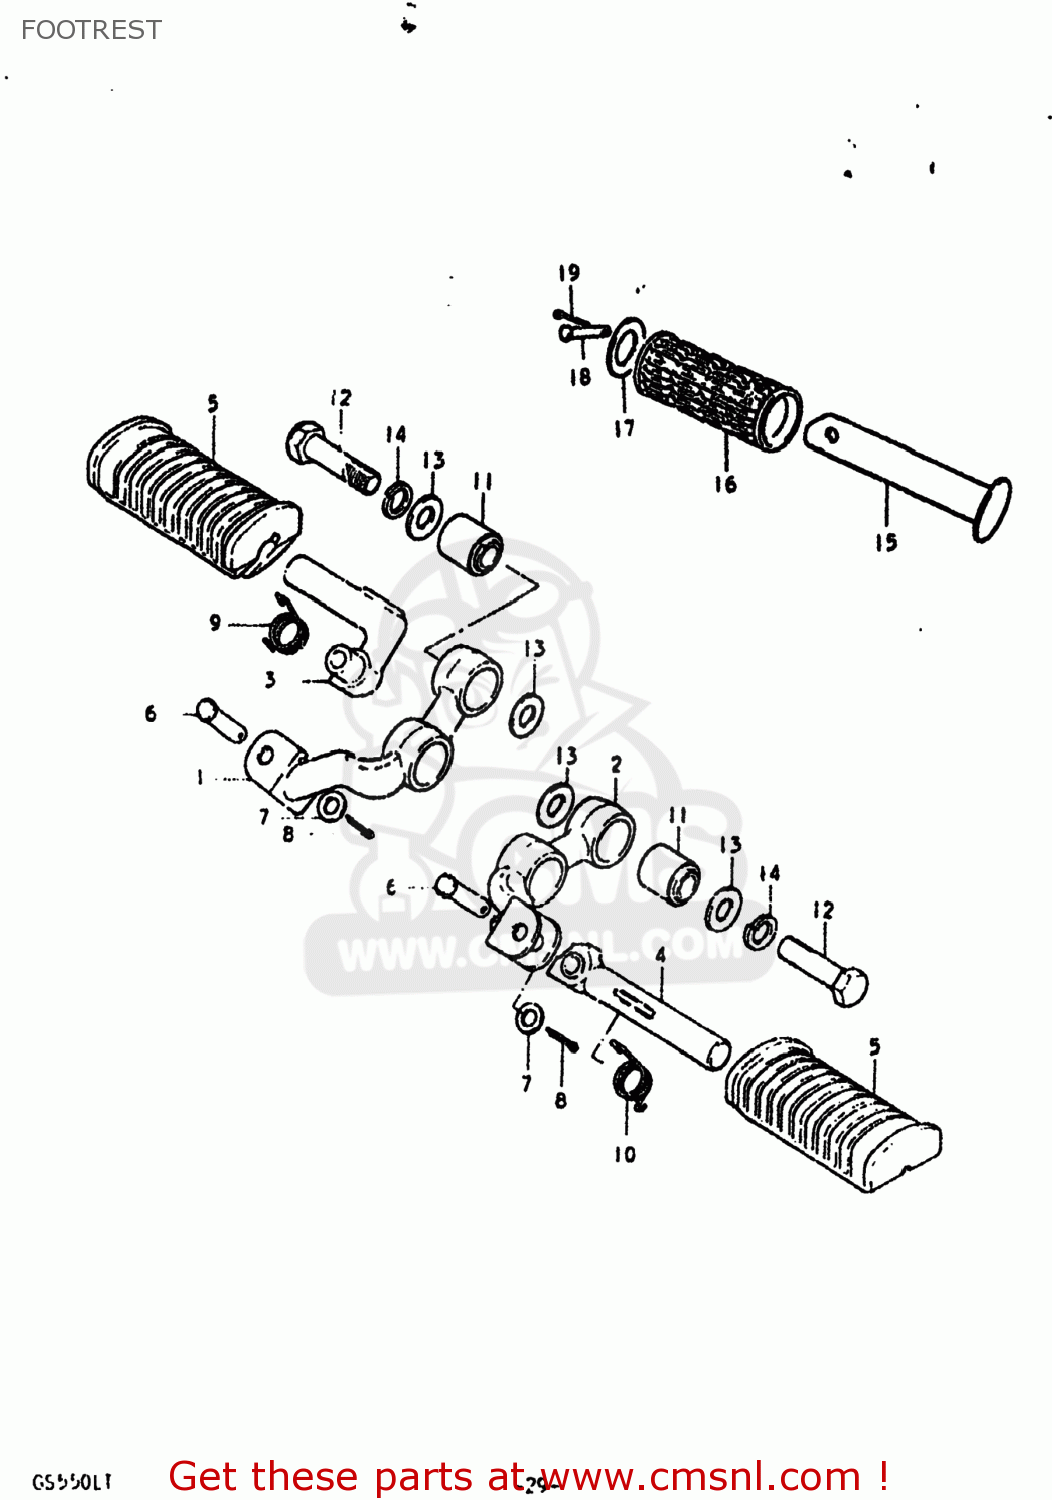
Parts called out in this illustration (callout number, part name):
1	BAR,FRONT FOOTREST,RIGHT
2	BAR,FRONT FOOTREST,LEFT
3	BAR,FRONT FOOTREST,RIGHT NO
4	BAR,FRONT FOOTREST,LEFT NO
5	RUBBER,FR FOOTREST
6	PIN
7	WASHER
8	PIN
9	SPRING
10	SPRING
11	BUSH
12	BOLT
13	WASHER (10.1X21X2.3)
14	LOCK WASHER
15	BAR,PILLION FOOTREST
16	RUBBER,REAR FOOTREST
17	WASHER (19.5X32X2)
18	PIN
19	PIN
